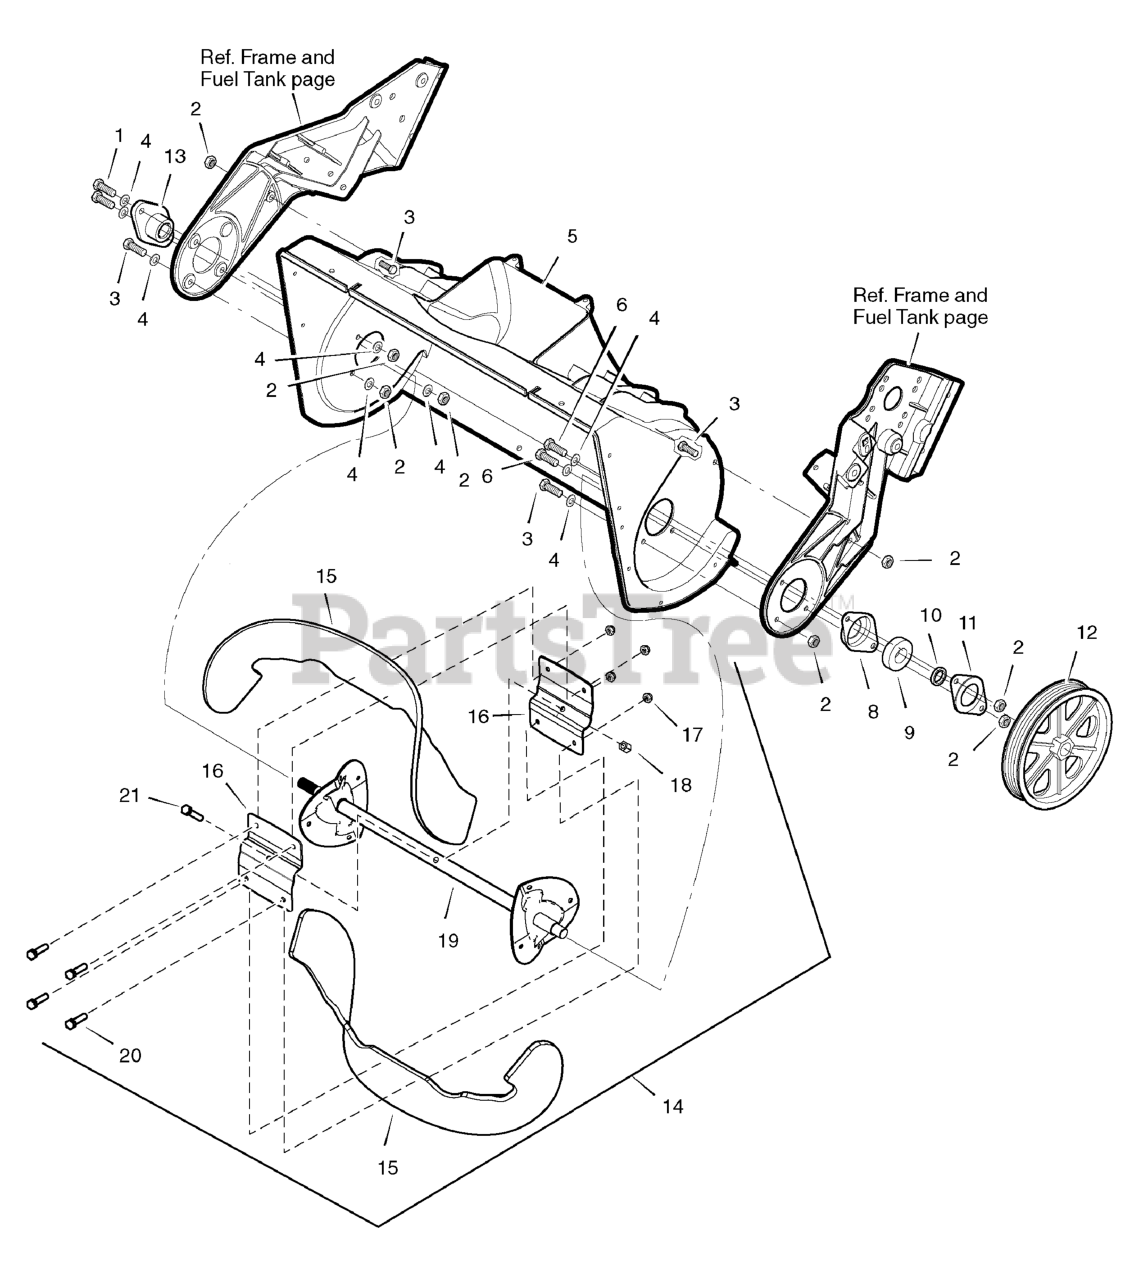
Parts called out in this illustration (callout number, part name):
1	SCREW, 1/4 - 20 x 1
2	NUT, Hex, 1/4 - 20
3	SCREW, 1/4 - 20 x 3/4
4	WASHER, Flat
5	HOUSING ASSEMBLY, Auger
6	SCREW, 1/4 - 20 x 5/8
8	BEARING, Retainer
9	Bearing
10	SLEEVE, Spacer
11	PLATE, Bearing Retainer
12	PULLEY, Auger Drive V6
13	BEARING, Flange
14	AUGER HOUSING
15	BLADE, Auger, Black
16	BRACKET, Auger, Center
17	NUT, Nylock
18	NUT, Hex-Lock, ESNA Light, 5/16-18, NC3B, Black
19	SHAFT, Sub
21	CAPSCREW, Hex-Head, 5/16-18 x 1-1/2, G5 Black
